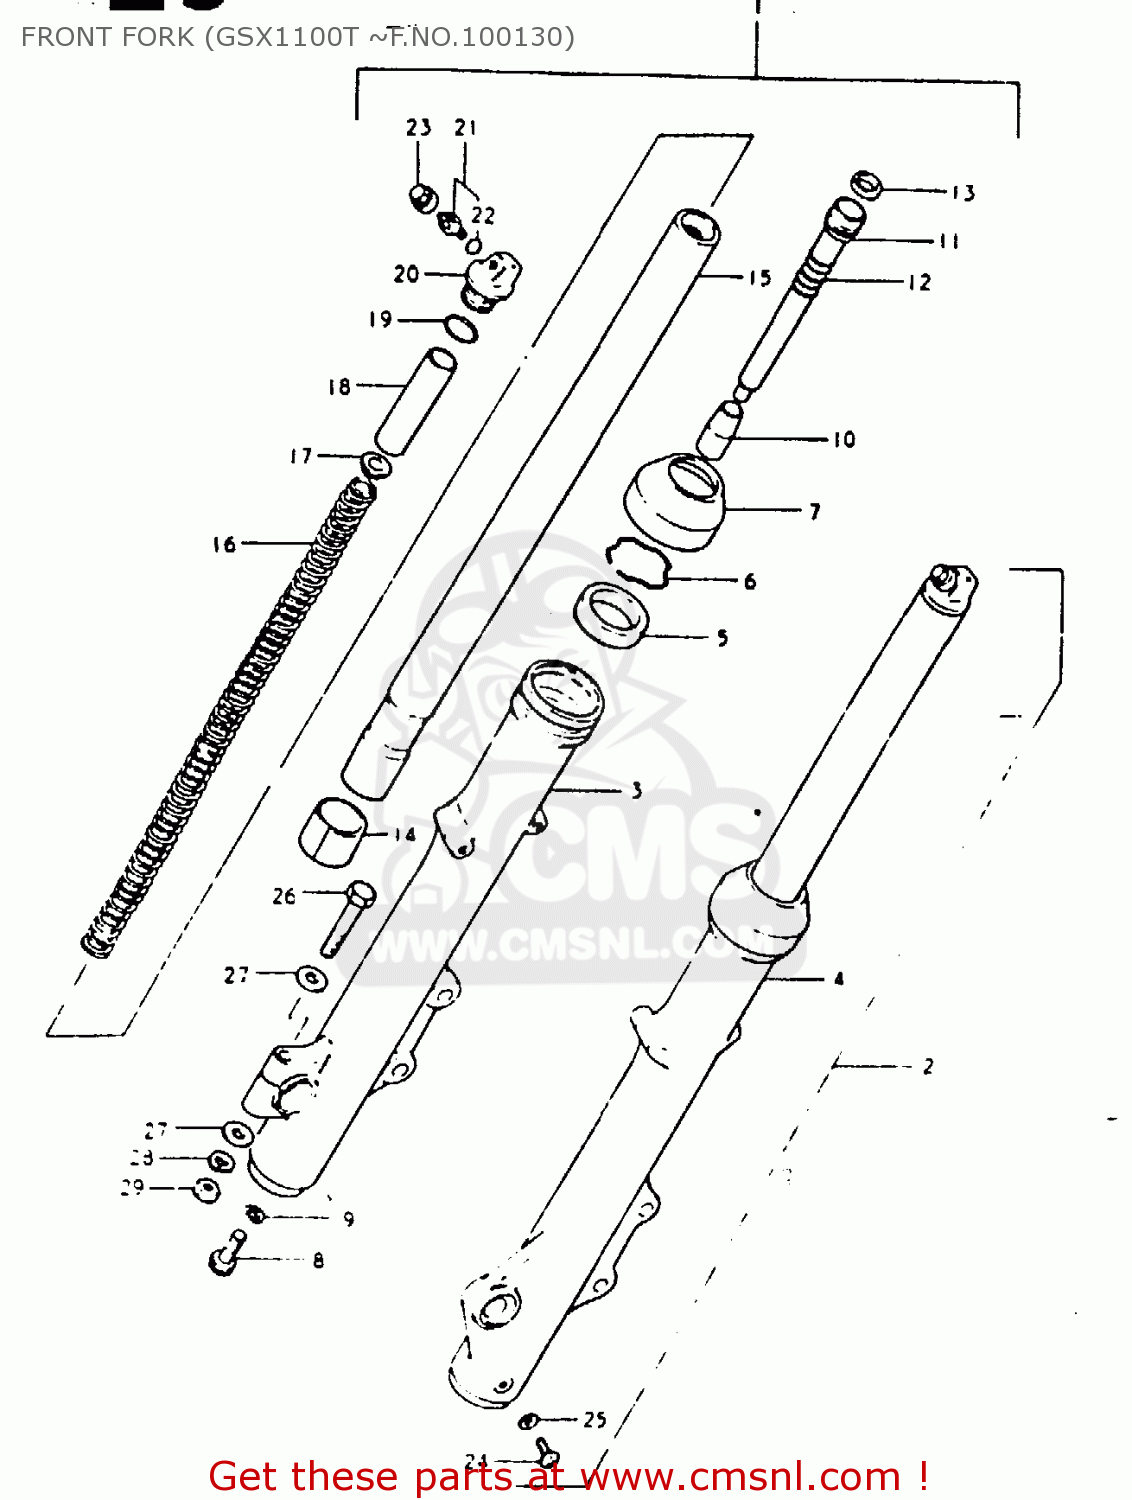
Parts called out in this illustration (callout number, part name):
1	DAMPER ASSY, RH
2	DAMPER ASSY, LH
3	TUBE,FORK,OUTER,RIGHT
4	TUBE,OUTER,LEFT
5	OIL SEAL,FRONT FORK
6	RING,STOPPER
7	SEAL,DUST
8	BOLT,FORK CYLINDER(10X25)
9	GASKET (NAS)
10	PIECE,OIL LOCK
11	CYLINDER
12	SPRING,FORK REBOUND
13	RING,PISTON
14	PISTON
15	INNER TUBE
16	SPRING
17	GUIDE,FRONT FORK SPRING C
18	SPACER,FRONT FORK SPRING
19	O RING
20	CAP
21	VALVE
22	O RING
23	CAP,VALVE
24	SCREW
25	GASKET,DRAIN,PLUG (NAS)
26	BOLT 8X50
27	WASHER
28	WASHER,LOCK,8.
29	NUT
